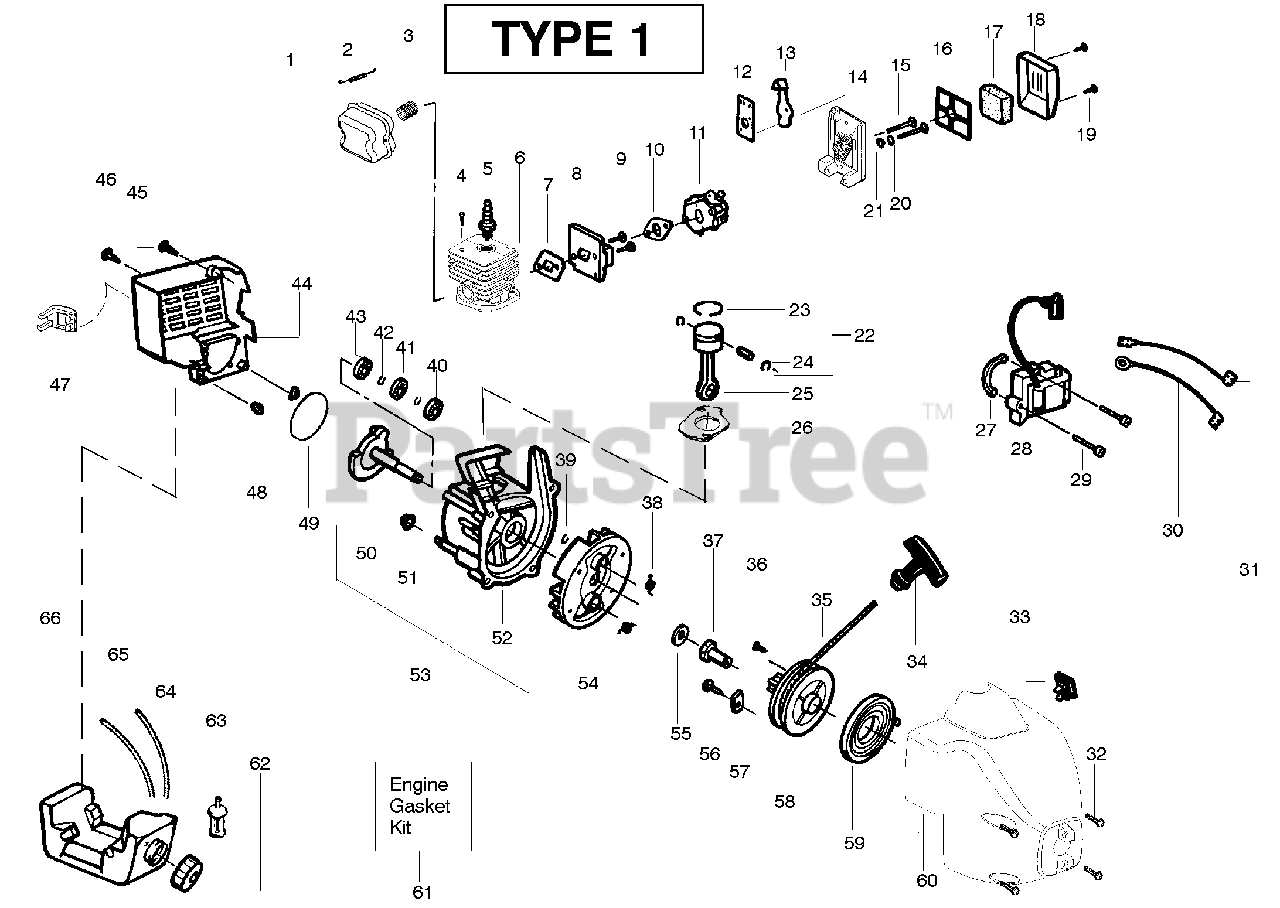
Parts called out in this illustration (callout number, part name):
1	Kit - Muffler
2	Muffler Spring
3	Screen-Spark Arrestor
4	Screw-Cylinder
5	Spark Plug (RCJ 8Y)
6	Kit - Cylinder
7	Gasket-Cylind./Carb.
8	Kit - Carb. Adaptor
10	Gasket-Carb.
11	Kit - Carburetor Ass'y
12	Choke Plate Mounting
13	Choke Shutter
16	Plate - Filter Support
17	Air Filter Foam
18	Air Filter Cover
20	Spacer-Choke
22	Kit - Piston
23	Piston Ring
24	Piston Pin Retainer
25	Connecting Rod Ass'y.
26	Gasket-Cylinder
27	Spacer-Module
28	Ignition Module
30	Ground Wire Ass'y.
31	Lead Wire Ass'y.
32	Screw
33	Kit - Switch
34	Starter Handle
35	Kit - Rope
37	Drive Coupling
38	Starter Dog Spring
39	Retain. Ring-C'shaft
40	Outer Bearing
41	C'case Seal
42	Retainer Ring-C'case
43	Inner Bearing
44	Rear Shroud
46	Screw
47	Guard-Muffler
48	Isolator-Shroud
49	O-Ring-C'case/Shrd
50	Crankshaft Ass'y.
51	Isolator-Crankcase
52	Crankcase Ass'y.
53	C'case & C'shaft Assy.
54	Flywheel Ass'y.
55	Washer-Flat
57	Retainer-Can
58	Starter Pulley Kit
59	Starter Spring
60	Assy. - Fan Housing
61	Kit-Engine Gasket
62	Fuel Cap Ass'y.
63	Fuel Pickup Ass'y.
64	Kit-Fuel Line (Small)
65	Kit-Fuel Line (Large)
66	Fuel Tank Ass'y
